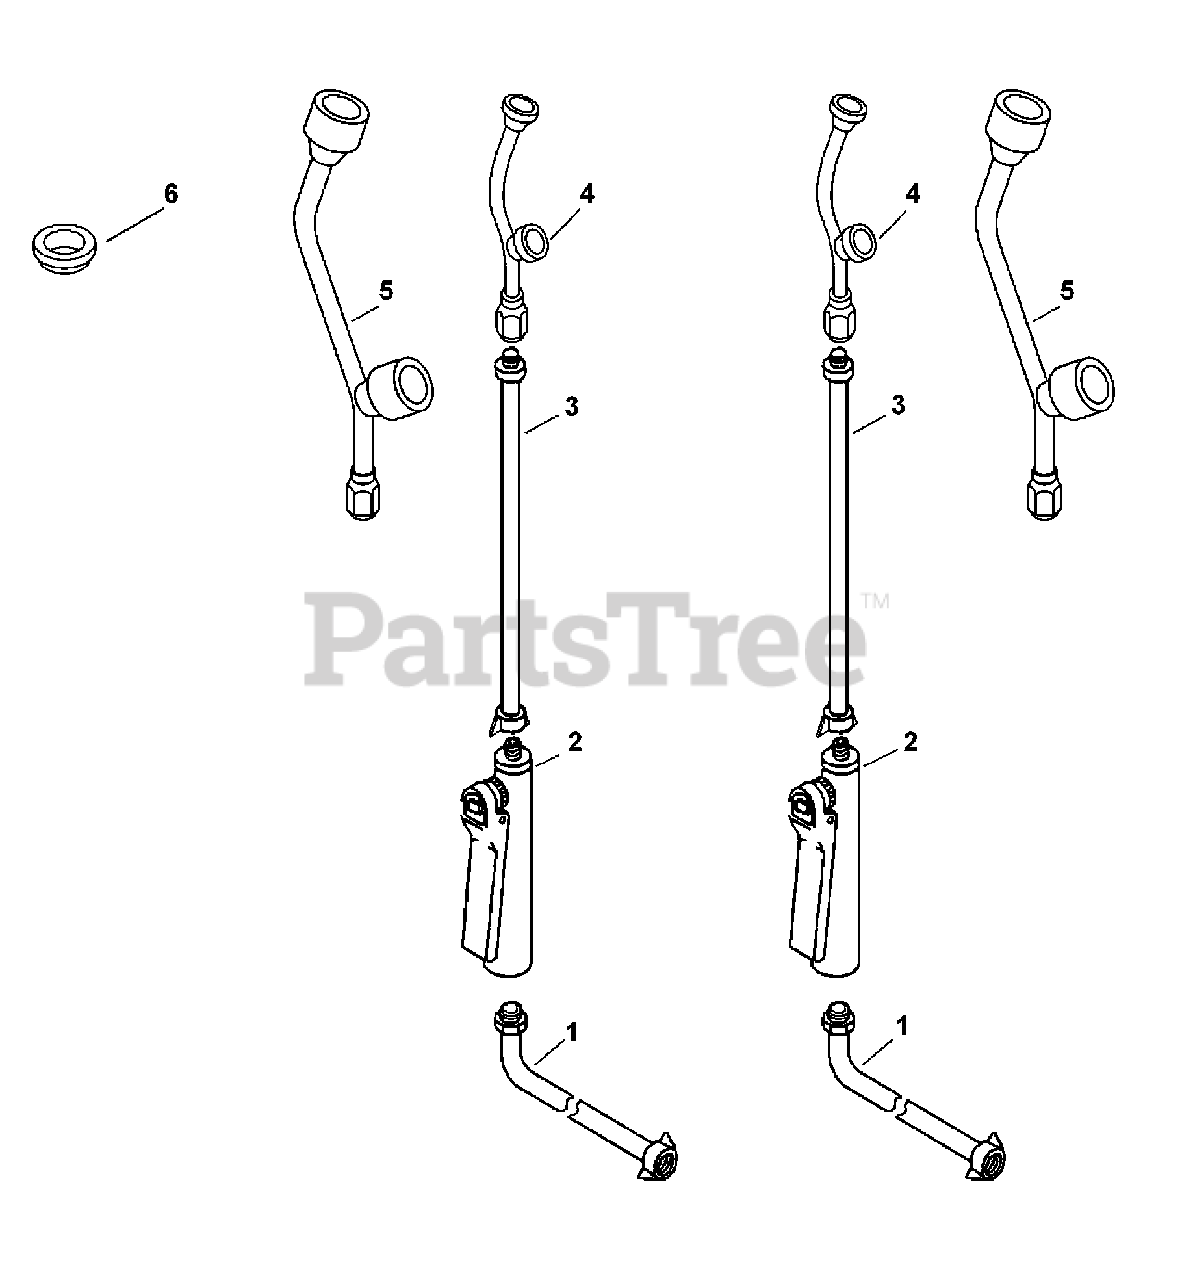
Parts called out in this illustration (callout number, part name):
2	HOSE ASSY, SPRAYER
3	GRIP, SPRAYER
4	VALVE, SPRAY
5	WAND, SPRAYER
6	NOZZLE-2, PLASTIC
